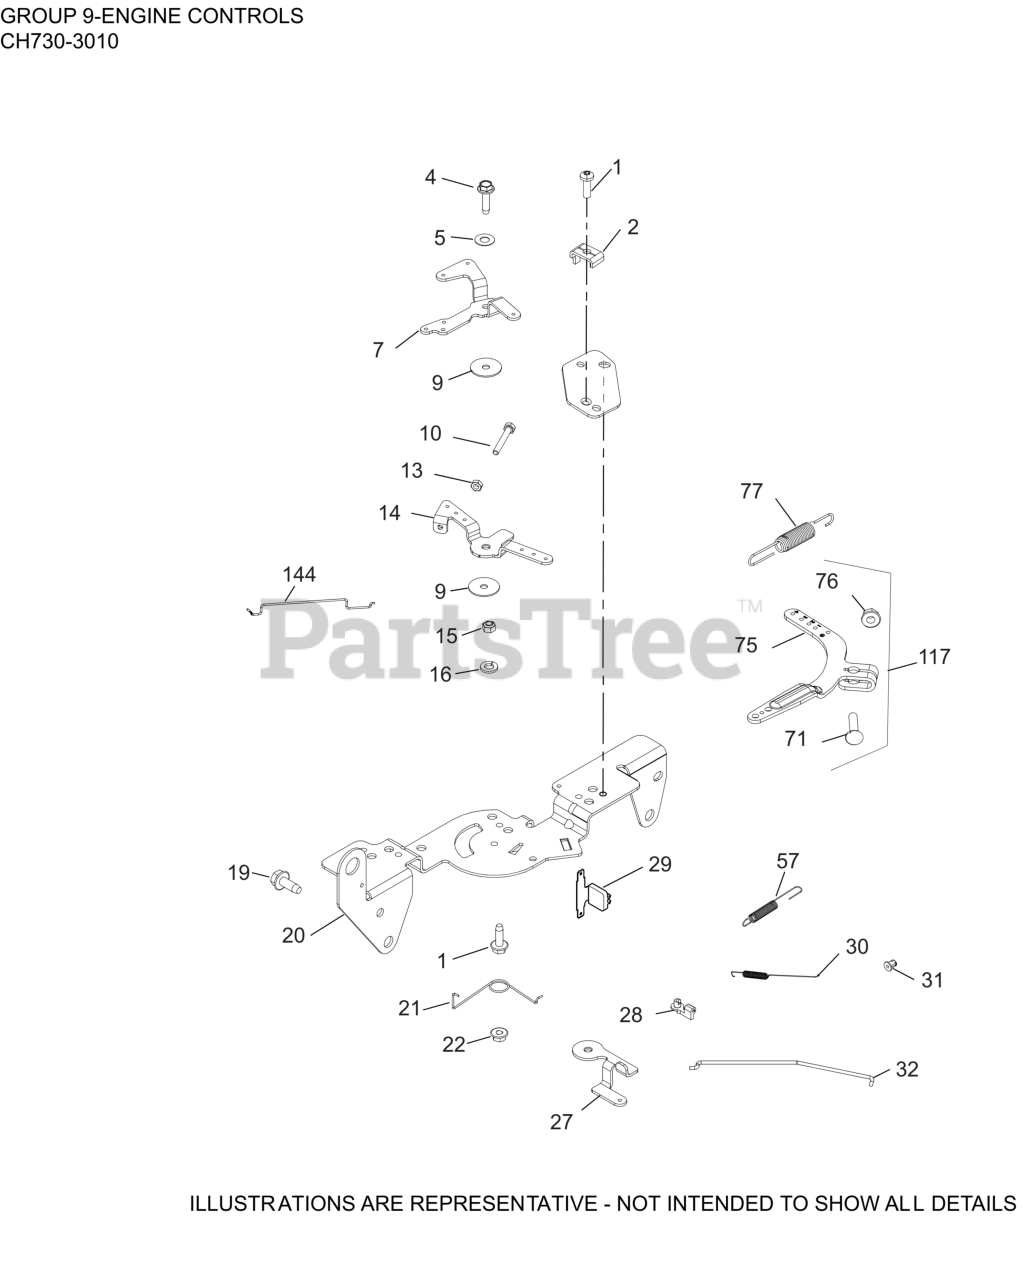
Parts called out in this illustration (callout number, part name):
1	SCREW, THREAD FORMING
2	CLAMP, CABLE CABLE
4	SCREW, THD FRM-USE 25 086 473-S
5	WASHER, SPRING 1/4"
7	LEVER, CHOKE
9	WASHER, FLAT 5.5 MM
10	SCREW, CAP M4X.7X30
13	NUT, M4X0.7
14	LEVER, THROTTLE CONTROL
15	NUT, FLG M5X.8
16	WASHER, SPRING LOCK 1/4"
19	SCREW, THREAD FORMING
20	BRACKET, CONTROL
21	SPRING, CHOKE RETURN
22	NUT, LOCK M5X.8
27	LEVER, THROTTLE ACTUATOR
28	BUSHING, THROTTLE LINKAGE
30	SPRING, LINKAGE
31	BUSHING, LINKAGE RETAINING
32	LINKAGE, THROTTLE
57	SPRING, THROTTLE LIMITER
71	BOLT, RD HD SQ NECK M6X1.0X25
75	LEVER, GOVERNOR - (#2409069S)
76	NUT, FLG M6X1.0
77	SPRING, GOVERNOR (BLACK)
117	LEVER, GOVERNOR ASSEMBLY
144	LINKAGE, CHOKE
